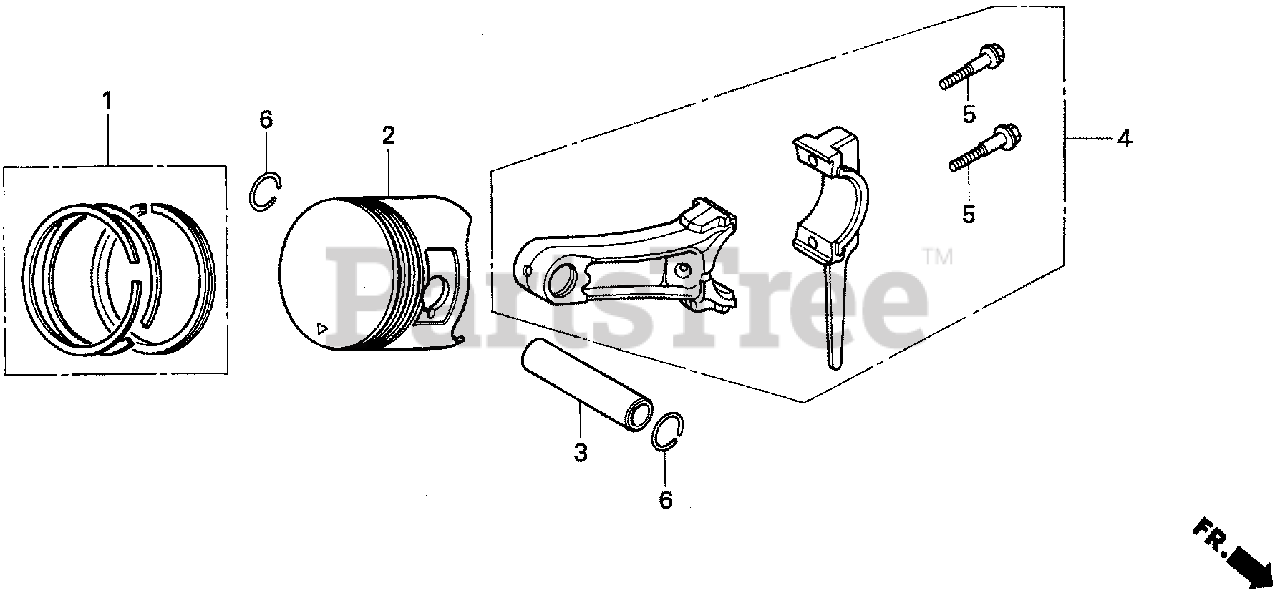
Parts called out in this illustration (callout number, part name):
1	RING SET, PISTON (STD)
1	RING SET, PISTON (OS 0.25)
1	RING SET, PISTON (OS 0.50)
1	RING SET, PISTON (0.75)
2	PISTON (STD)
2	PISTON (OS 0.25)
2	PISTON (OS 0.50)
2	PISTON (0.75)
3	PIN, PISTON
4	ROD ASSY., CONNECTING (US 0.25)
4	ROD ASSY., CONNECTING
5	BOLT, CONNECTING ROD
6	CLIP, PISTON PIN (18MM)
